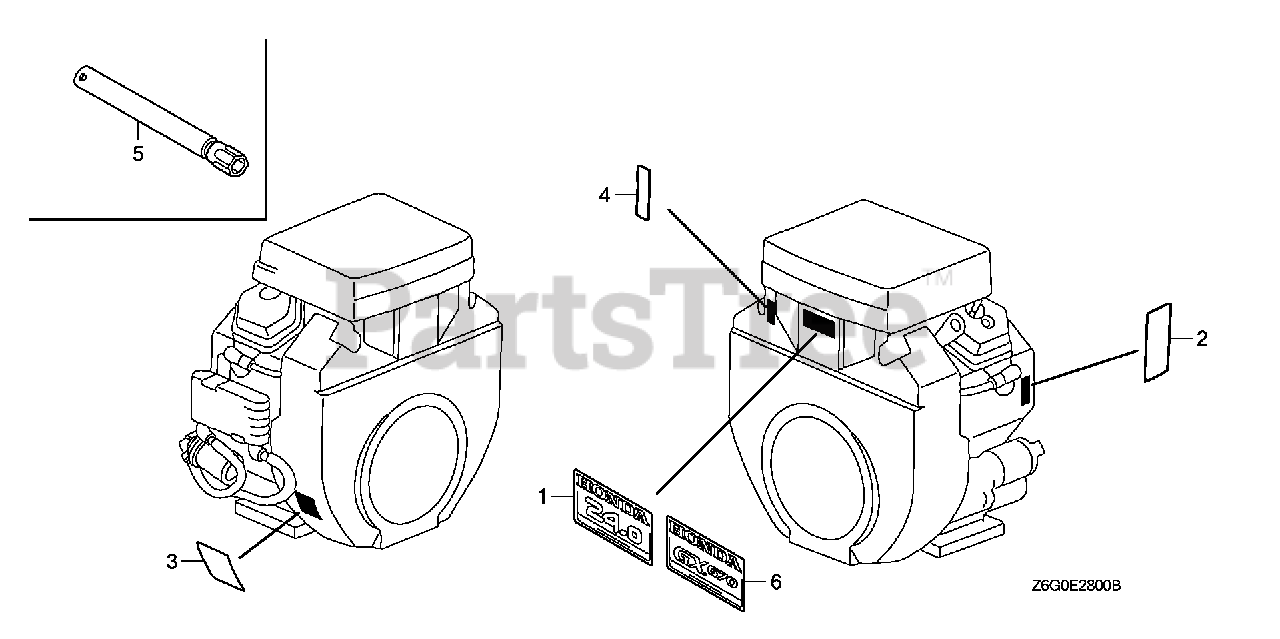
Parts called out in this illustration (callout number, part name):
1	EMBLEM (24.0)
1	EMBLEM (GX670)
2	LABEL, SPECIFICATION (GX670)
3	MARK, OPERATOR CAUTION (ENGLISH)(MADE IN JAPAN)
3	MARK, OPERATOR CAUTION (PICTOGRAPH)(MADE IN JAPAN)
5	WRENCH, SPARK PLUG
6	EMBLEM (GX670)
